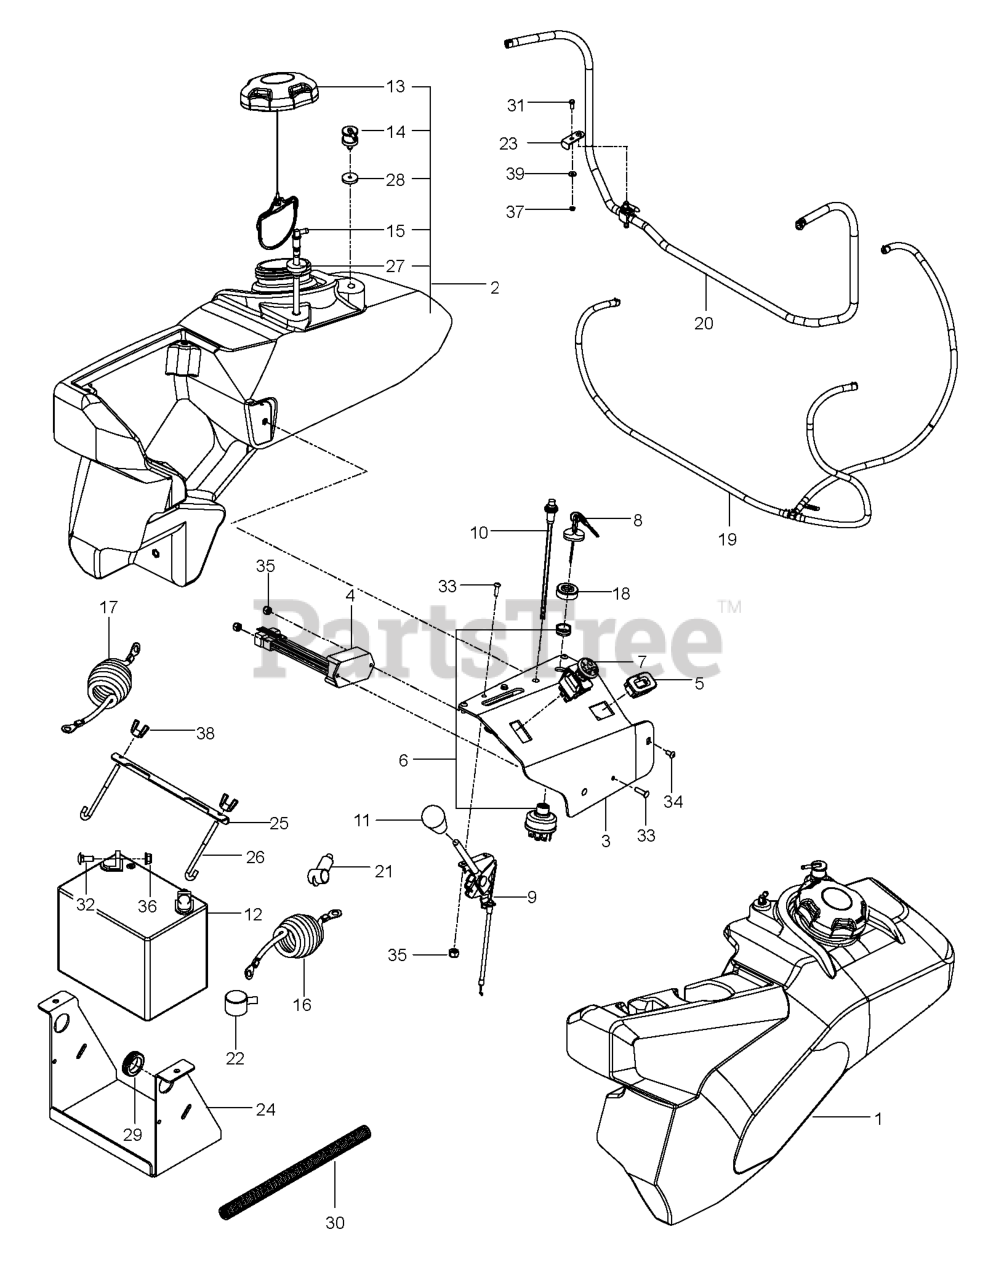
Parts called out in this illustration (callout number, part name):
1	FUEL TANK LH PZ GRAY
2	FUEL TANK ASM RH GRAY PZ
3	PANEL.CONTROL.GAS.GRAY
4	TIMER, SEAT
5	GUAGE.SRVCMNDR.HRMTR.
6	SWITCH, IGNITION, INDAK
7	RP SWITCH.PTO.TERMINAL.STD.RED
8	KEY, IGNITION
9	CABLE, THROTTLE, 46"
10	LED.LIGHT.SERVICE.EFI
11	KNOB - SHIFT
12	BATTERY, 12 V 330 AMP
13	CAP, FUEL
14	VALVE.FUEL.CHECK
15	FITTING, FUEL
16	CABLE, POSITIVE, 55"
17	CABLE, NEG, 55"
18	CAP IGNITION NUT
19	HOSE.ASM.VAPOR.LINE.36-10-21
20	ASSEMBLY, FUEL LINE
22	BATTERY.CABLE.BOOT.RED.MZ.PZ.E
23	BRACKET,FUEL VALVE, BLACK
24	BRACKET, BATTERY, BLK
25	BRACKET, BATTERY MOUNT
26	HOOK, "J"
27	RUBBER GROMMET
28	GROMMET, CHECK VALVE
29	RUBBER GROMMET
30	LOOM, SPLIT, CONVOLUTED
31	HCS 1/4C X 3/4 HCS
32	RP BOLT 5/16-18 X3/4 ZN/YEL GR
33	SCR #10-24 X .75 SKT HD BLK
34	SCR #10-24 X 3/8 SKT HD BLK OX
35	NUT 10-24 NYLOC
36	5/16-18 NYLOC FLANGE NUT
37	JAM NUT 1/4C (2 2 PW01)
38	WING NUT 1/4
39	WASHER 1/4 FLAT
